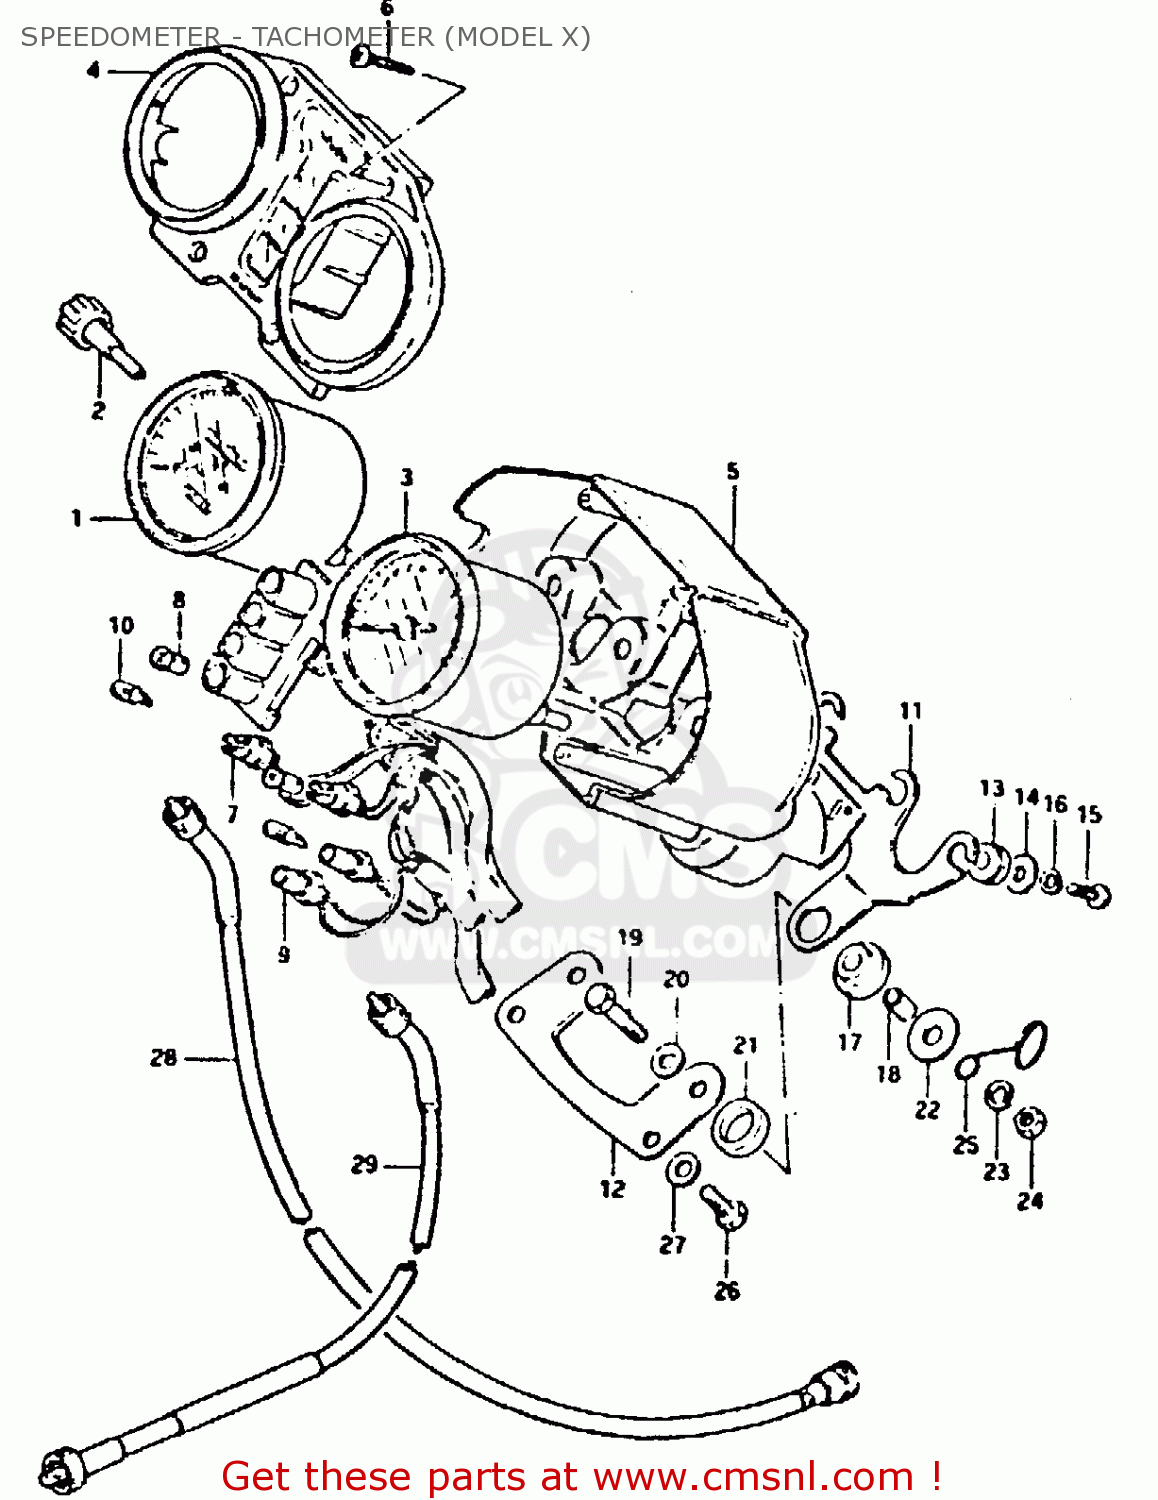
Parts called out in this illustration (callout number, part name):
1	METER,SPEEDOMETER (KM/MPH)
2	KNOB,TRIP METER
3	TACHOMETER
4	HOOD
5	VISOR,LWR
6	SCREW
7	SOCKET
8	BULB(12V3.4W,STANLEY,A72A)
9	SOCKET
10	BULB(12V3.4W,T10)
11	BRACKET, NO. 1
12	BRACKET, NO. 2
13	CUSHION
14	WASHER,METER
15	SCREW
16	LOCK WASHER
17	CUSHION
18	SPACER
19	BOLT
20	WASHER
21	CUSHION
22	WASHER (6.5X24X1.6)
23	LOCK WASHER
24	NUT
25	CLIP
26	BOLT, UPPER
27	WASHER
28	CABLE, SPEEDOMETER
29	CABLE ASSY,TACHOMETER
